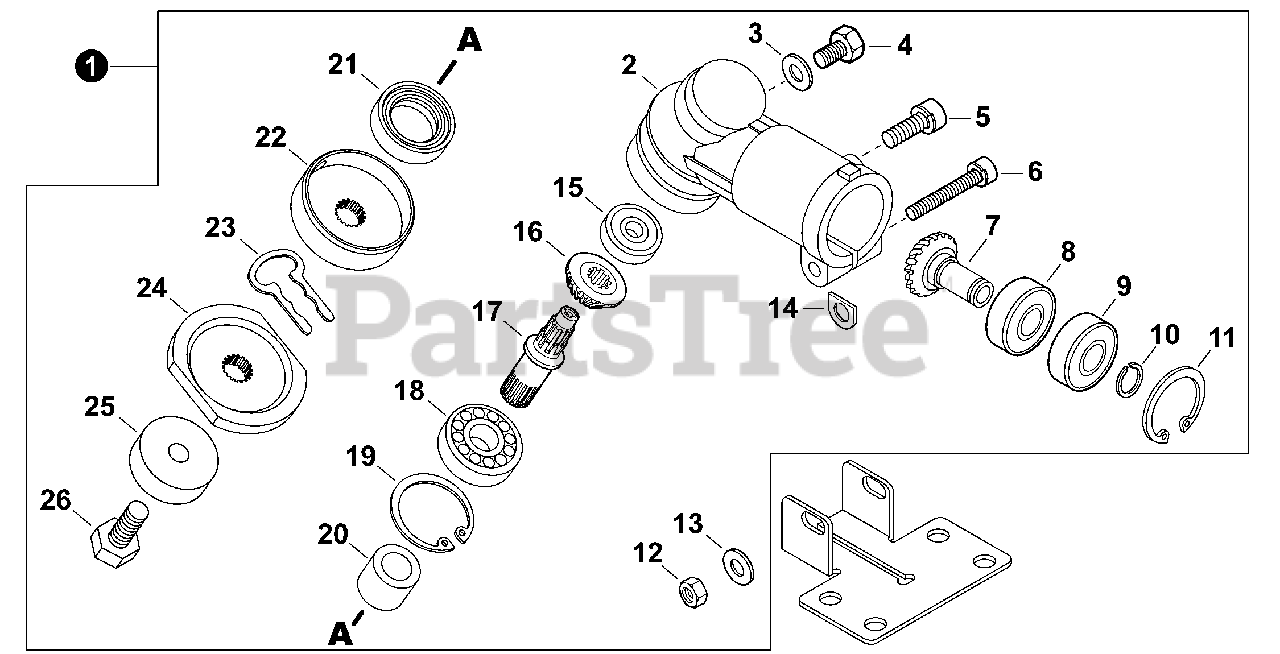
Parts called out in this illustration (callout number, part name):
1	GEAR CASE ASSY
2	HOUSING, GEAR CASE
4	BOLT M6×10
5	BOLT M5×16
6	BOLT M5×35
7	GEAR, PINION
8	BEARING, BALL 608
9	BEARING, BALL 608ZZ
10	E-RING 8
11	RING, SNAP Ø22
13	WASHER 5.5×12×0.8
14	D-WASHER
15	BEARING, BALL 626 DDU
16	GEAR, BEVEL
17	SHAFT, GEAR
18	BEARING, BALL 6000
19	RING, SNAP Ø26
21	SEAL, OIL
22	PLATE, ADAPTOR - UPPER
23	CLIP, BLADE
24	PLATE, ADAPTOR - LOWER
25	GUARD, BOLT
26	BOLT M7×18
